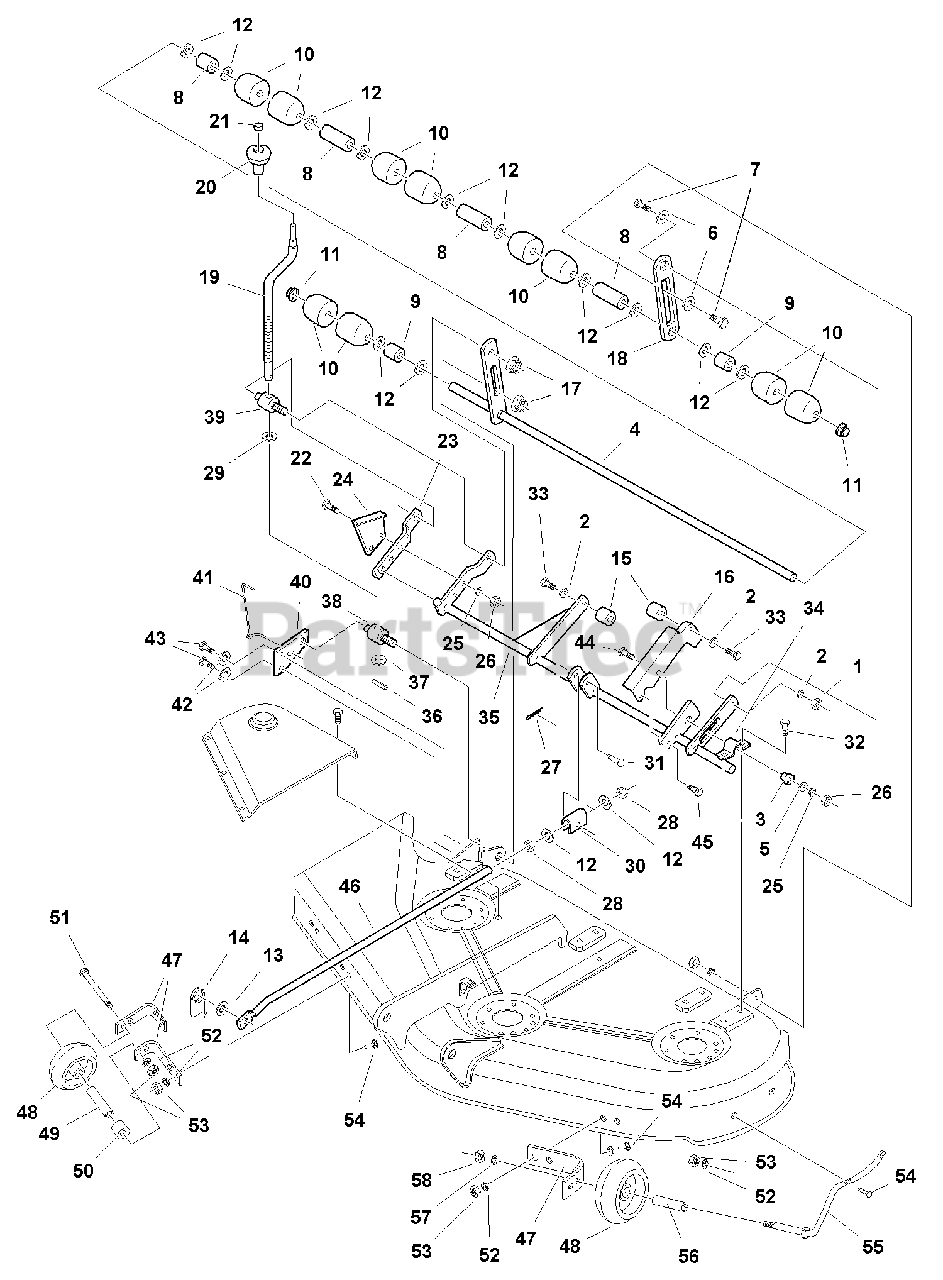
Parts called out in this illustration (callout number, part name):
1	NUT, Hex, 3/8-16
2	LOCKWASHER, 3/8
3	NUT, Adjuster, Eccentric
4	SHAFT ASSEMBLY, Roller, 50" (Includes Ref. Nos. 9 & 11)
5	WASHER ,Plain, 7/8
6	WASHER, Plain, 1/2
7	BOLT, Shoulder, 3/8-16 X 1.34
11	NUT, Push
12	WASHER, 5/8
13	WASHER, Plain, 13/32
14	CLIP, Pin, Safety
16	ARM, Rear, Adjustable
17	NUT, Hex Flange Lock, 1/2-13
18	BAR, Roller
19	CRANK, Cutting Height
20	KNOB, Height Crank
21	PAL NUT
22	CAPSCREW, Hex Head, 5/16-18 x 1-1/4
23	ARM, Rear, Mower, RH
24	BRACKET, Cutting Height
26	NUT, Hex, 5/16-18 Whiz Lock
27	PIN, Hair Clip
28	NUT, Hex Jam, 3/4-11
29	WASHER, 5/8
30	TRUNNION
31	PIN, Clevis
32	CAPSCREW, Taptite, 5/16-18 x 3/4
33	CAPSCREW, Hex Head, 3/8-16 x 1
34	STRAP, Mower Arm Assembly
35	ARM ASSEMBLY, Mower
36	PIN, Roll, 1"Long
37	WASHER, Detent
39	TRUNNION, Threaded
40	PLATE, Mower Support
41	INDICATOR, Cutting Height
42	WASHER, Flat, 5/16
43	CAPSCREW, Taptite, 5/16-18 x 1-1/4
44	CARRIAGE BOLT, 5/16-18 x 1-1/4
45	CAPSCREW, Taptite, 5/16-18 x 7/8
46	ROD, Adjustment
47	BRACKET, Anti-Scalp Roller
48	WHEEL, Gauge
51	CAPSCREW, Hex Head, 5/16-18 x 4 1/2
52	LOCKWASHER, 5/16
53	NUT, Hex, Full, 5/16-18
54	CARRIAGE BOLT, 5/16-18 x 7/8
55	ROD ASSEMBLY, Roller, LH
57	LOCKWASHER, 3/8
58	NUT, Hex, Full, 3/8-16
